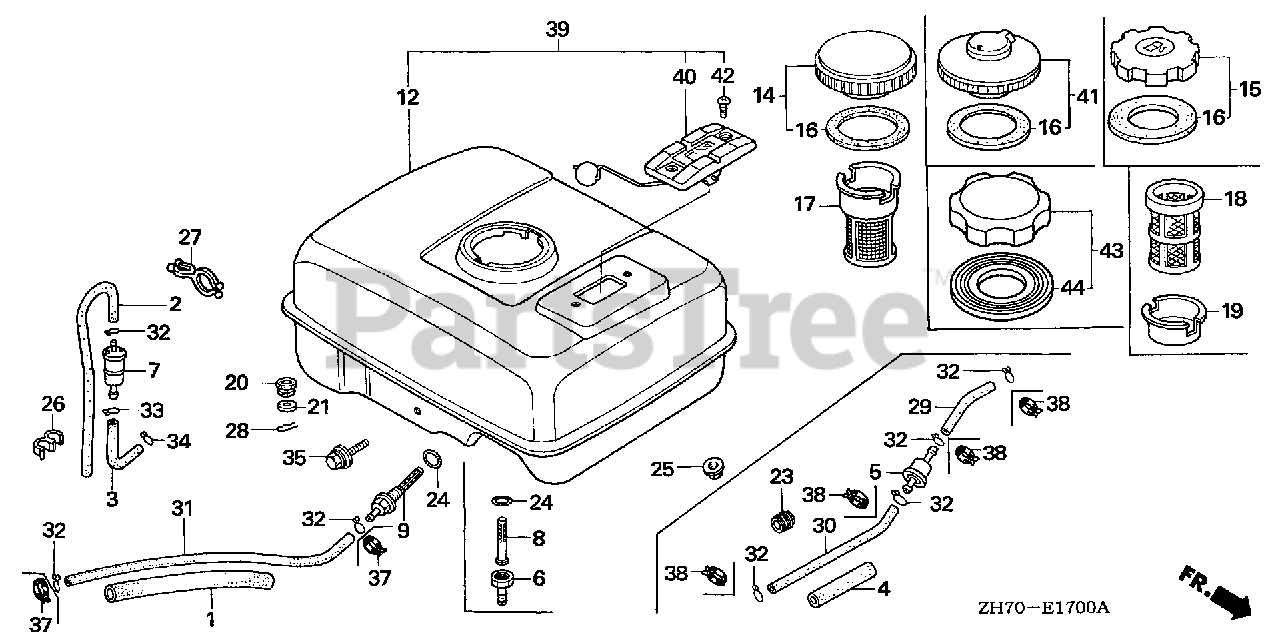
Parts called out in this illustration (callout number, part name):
1	RUBBER, SUPPORTER (107MM)
9	JOINT, FUEL TANK
12	TANK, FUEL *NH31* (MCKINLEY WHITE)
12	TANK, FUEL *NH1* (BLACK)
14	CAP, FUEL FILLER
15	CAP, FUEL FILLER (BLACK)
16	GASKET, FUEL FILLER CAP (39X58X3)
17	FILTER, FUEL
18	FILTER, FUEL
19	HOLDER, FUEL FILTER
24	O-RING (13.5X1.5) (ARAI)
24	O-RING (14MM) (NOK)
25	NUT, FLANGE (6MM)
31	BULK HOSE, FUEL (4.5X3000) (4.5X140)
32	CLIP, TUBE (B8)
35	BOLT, FLANGE (6X25)
43	CAP, FUEL FILLER (CHROME PLATED)
43	CAP, FUEL FILLER (CHROME PLATED)(TOUYOUSYA)
44	GASKET, FUEL FILLER CAP (39X62X3) (TOUYOUSYA)
